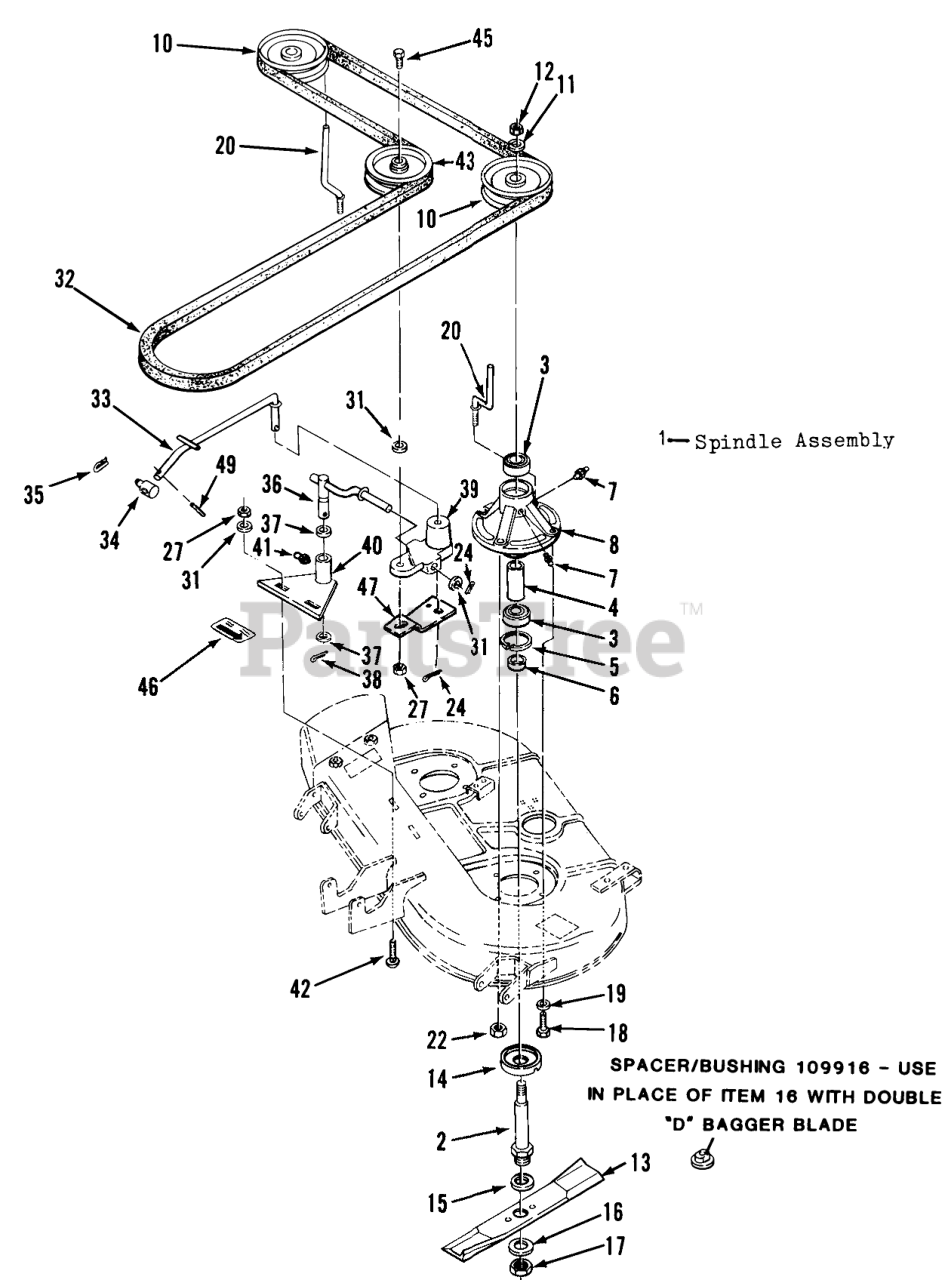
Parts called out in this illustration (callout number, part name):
1	Spindle Assembly, Metric Bearings (includes items 2 thru 8 & 14)
2	SHAFT SPINDLE
3	BEARING-BALL
5	Ring-Snap
6	SPACER-BLADE
7	Fitting-Grease
8	HOUSING SPINDLE
10	PULLEY-BLADE
11	Lockwasher
12	Jam Nut
13	ASSY BLADE KIT
14	CUP-SPINDLE
15	Washer
16	SpeciaI Washer
17	Nut-Jam
18	BOLT
19	LOCKWASHER
20	ROD-GUIDE
22	NUT
24	Pop Rivet
27	NUT
31	Washer
32	Drive Belt
33	ASS'Y-ROD IDLER B
34	TRUNNION-LIFT
35	Hairpin Cotter
36	ARM ASSEMBLY R
37	WASHER
38	Cotter Pin
39	BLOCK IDLER
40	IDLER BRACKET ASS R
41	FITTING-GREASE
42	Bolt
43	PULLEY-FLAT IDLER
45	Bolt
46	DECAL-BELT ADJUST
47	ANCHOR-SPRING B
49	Pin-Roll
